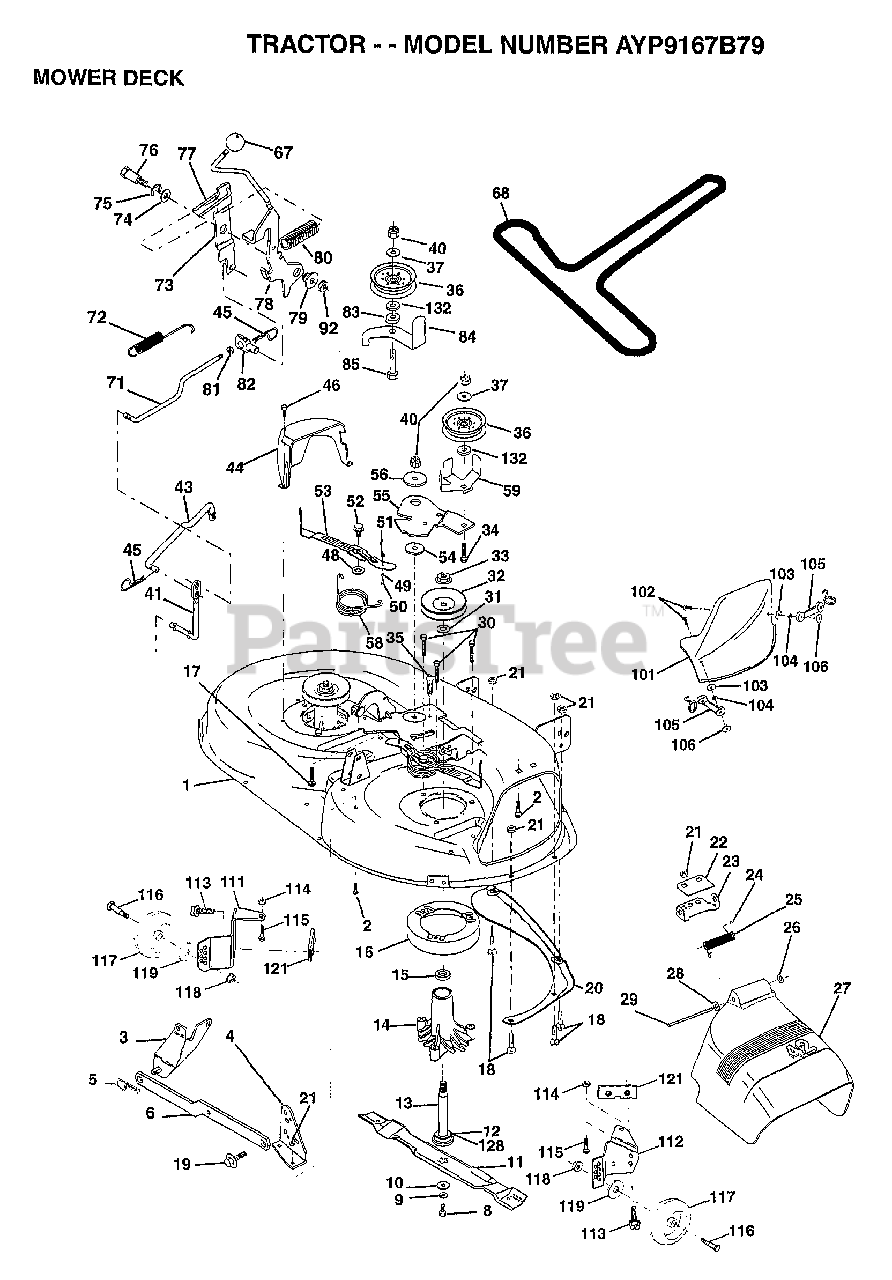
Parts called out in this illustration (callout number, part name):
1	DECK.WELD.42.
2	BOLT
3	BRKT ASM SWAY BAR
4	BRKT DECK SW BAR
8	BLADE BOLT
10	WASHER.HARD.BLADE
11	"BLADE.42"" MULCHER"
12	BEARING.BALL
14	HSG ASM MANDREL
15	BEARING
16	STRIPPER RND MWR
17	BOLT RDHD 3/8-16
18	BOLT
19	BOLT SHD 5/16-18
22	STIFFENER BRKT
23	DEFLECTOR BRKT
24	CAP-SLEEVE LT
25	SPRING TORSION
26	NUT PUSH M
27	DEFLECTOR.SHIELD
28	WASHER
29	HINGE ROD
30	"SCREW-THD ROLL,WA"
31	WASHER
32	PULLEY.MANDREL.42
34	BOLT
35	XMAS TREE FASTNER
36	FLAT IDLER PULLEY
37	WASHER
41	PIVOT ROD
43	ROD CLUTCH W/NIBS
44	GUARD MAND LH BLK
45	RETAINER M
46	SCREW.1/4-20X5/8
48	HARD SMALL WASHER
49	ROLLER ASM-CAM
50	SHOULDER BOLT
51	LOCKNUT
52	BOLT.SHLD.5/16-18
54	HARDENED WASHER
55	ARM-IDLER
56	SPACER RETAINER
58	SPRING TORSN BRAK
59	GUARD IDLER TUV
67	KNOB T(3/8 HOLE)
68	BELT.V.T-PATH
71	ROD CLUTCH 38/42
72	RETURN SPRING
73	CLUTCH ARM SECOND
74	WASHER
75	RING
76	SHOULDER BOLT
77	SPRING KEEPER
78	LEVER ASM-CLUTCH
79	BUSHING
80	SPRING.CLUTCH.MWR
81	TRUNION ADJ
82	NUT
83	WASHER
84	"KEEPER-BELT,FIXED"
85	BOLT RDHD 3/8-16
92	NUT
101	"COVER.MULCH.42"""
102	SCREW
103	WASHER #10
104	LOCKWASHER
106	WELDNUT
111	BRACKET.GWHL.LH.
112	BRACKET.GWHL.RH.
113	SCREW
116	BOLT.SHOULDER
117	WHEEL GAGE DONUT
118	LOCKNUT
119	WASHER
121	BRACKET.EXTRD.GWL
128	WASHER.FELT.
132	WASHER GT
